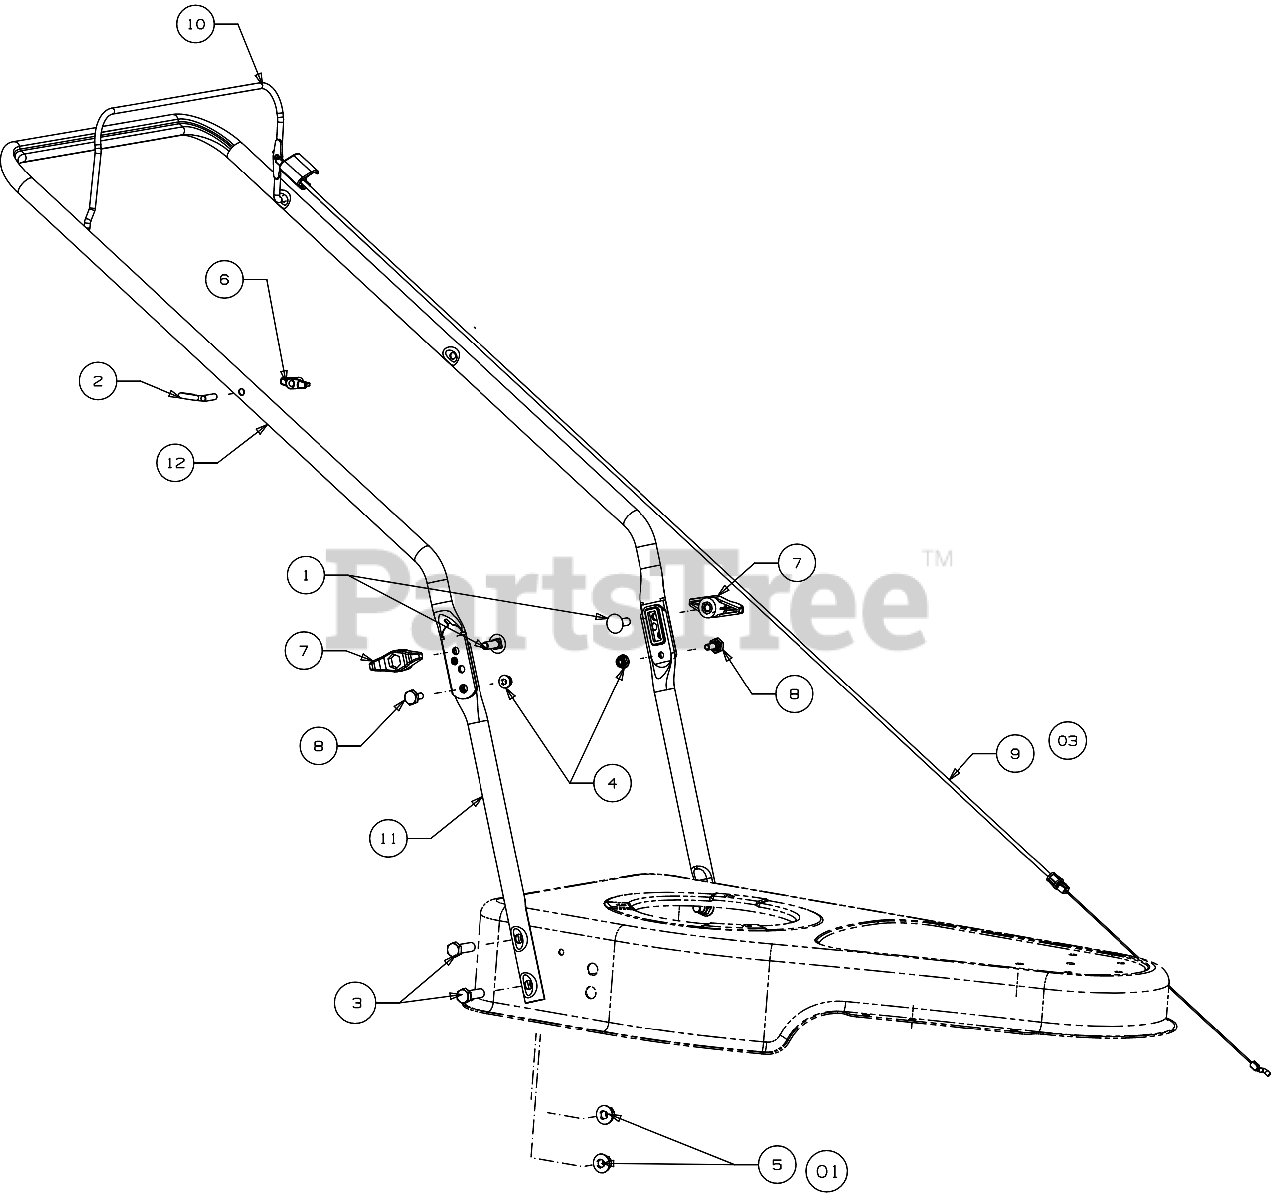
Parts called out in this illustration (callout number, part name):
1	SCREW 5/16-18 x 1.00 GR5
2	EYEBOLT 1/4-20
3	SCREW 3/8-16 x 1.25 GR5
4	FLANGE LOCK NUT
6	HANDLE KNOB
7	SCREW M12-1.75X50 GR8
8	SHOULDER SCREW
9	CONTROL CABLE 40"
